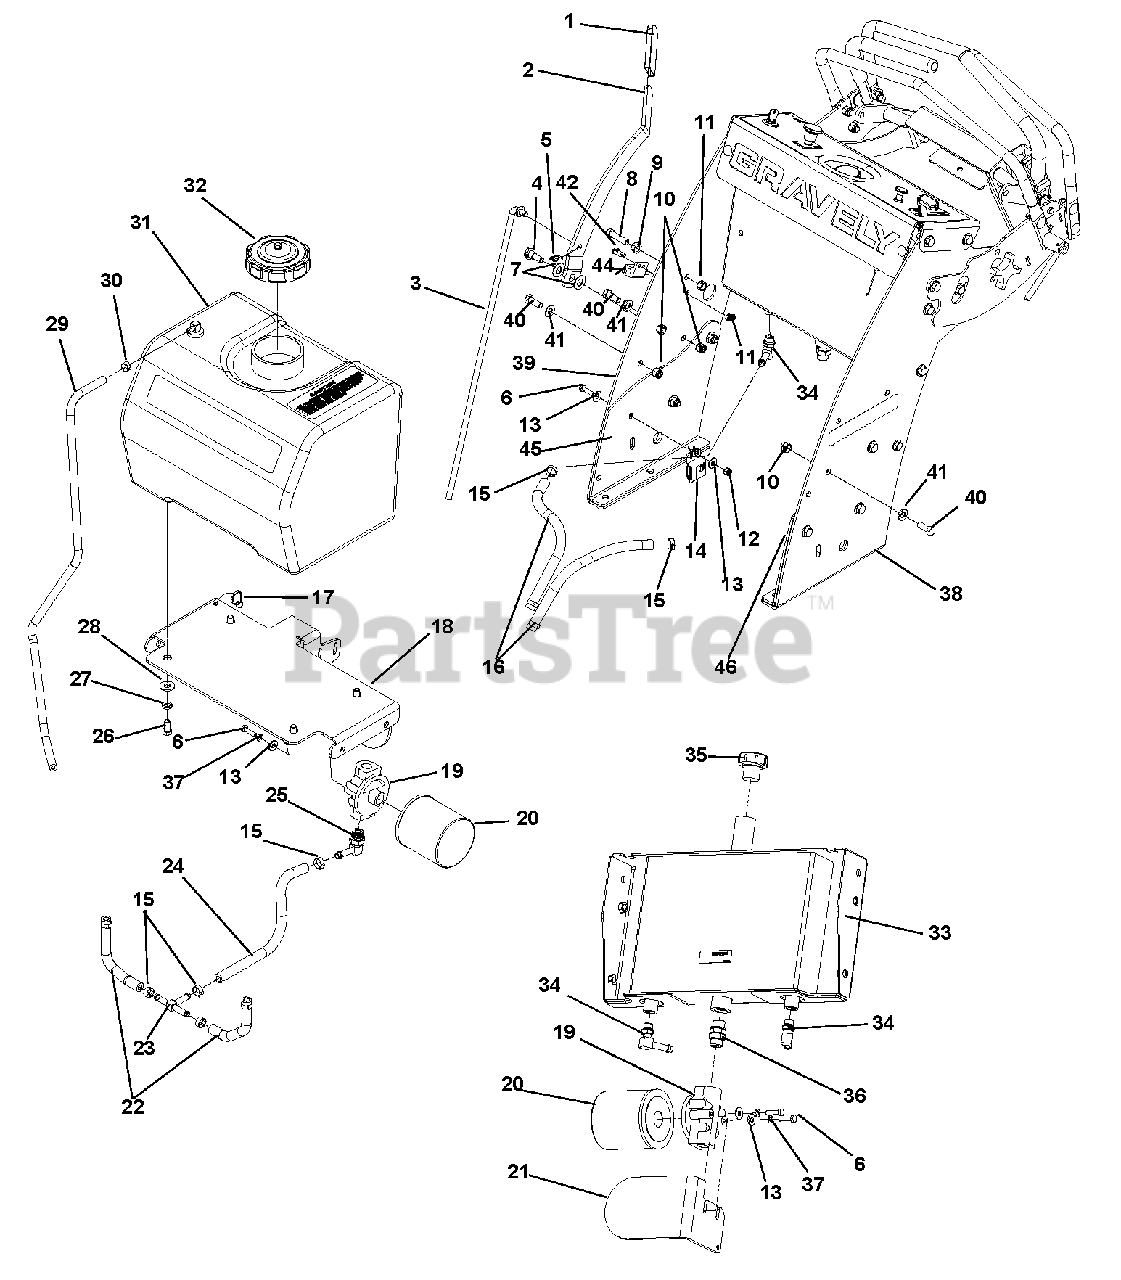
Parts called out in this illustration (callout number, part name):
1	GRIP, PVC .250 X 1.00 X 3.63
2	LEVER, HAND BRAKE FLOAT WALK
3	ROD, DRIVE CONTROL FW
4	BOLT, 1/2 X 1.06 X 3/8-16 SLD 5 Y
5	RING, RUE .375 x .054 x 1.254
6	BOLT, HEX .25-20 X 1.00 GR5 Y
7	WASHER, .510 X 1.00 X .068 NYLON
8	BOLT, HEX .38-16X1.50 GR5 Y
9	LOCKNUT, 3/8-16 WHIZ Y
10	LOCKNUT, 3/8-16 NYLOC Y
11	LOCKNUT, 3/8-16 CENTER Y
12	LOCKNUT, 1/4-20 NYLOC Y
13	WASHER, .250 REG FLAT Y
14	MODULE, ELECTRONIC
15	CLAMP, HOSE - 1/2" PINCH
16	HOSE, HYD .375 X 10
17	CABLE TIE, .15 X 8.50
18	BRACKET, FUEL TANK RMHF
19	HEAD, OIL FILTER
20	FILTER, OIL
21	GUARD, HYDRO FILTER FLWLK
22	HOSE, HYD 3/8 X 6.00
23	FTG, TUN 3/8 HOSE
24	HOSE, HYD. .375 X 12
25	FTG, 90 BRB-OR 4601-06-08
26	BOLT, HEX .38-16 X .75 GR5 Y
27	WASHER, .375 MED SPRG LOCK Y
28	WASHER, .375 REG FLAT Y
29	HOSE, FUEL 1/4 X 30.00
30	CLAMP, FUEL LINE
31	TANK, FUEL
32	CAP, FUEL
33	WLDT, TANK
34	FTG, 90 9/16 MOR X 3/8 HOSE
35	CAP, OIL FILL BREATHER
36	STRAIGHT UNION SAE 8
37	WASHER, .250 MED SPRG LOCK Y
38	WLDT, LH UPRIGHT TOWER 36
39	WLDT, RH UPRIGHT TOWER 36
40	BOLT-HEX .38-16 X 1.00 GR5 Y
41	WASHER, .406X.813 X .065 FLAT
42	SCREW, 10-24X.625 PAN PHL
43	LOCKNUT, 10-24 Nyloc Y
44	SWITCH- DOUBLE POLE N.O./N.O.
45	PLATE, DOUBLE RH UPRIGHT BI
46	PLATE, DOUBLE LH UPRIGHT BI
